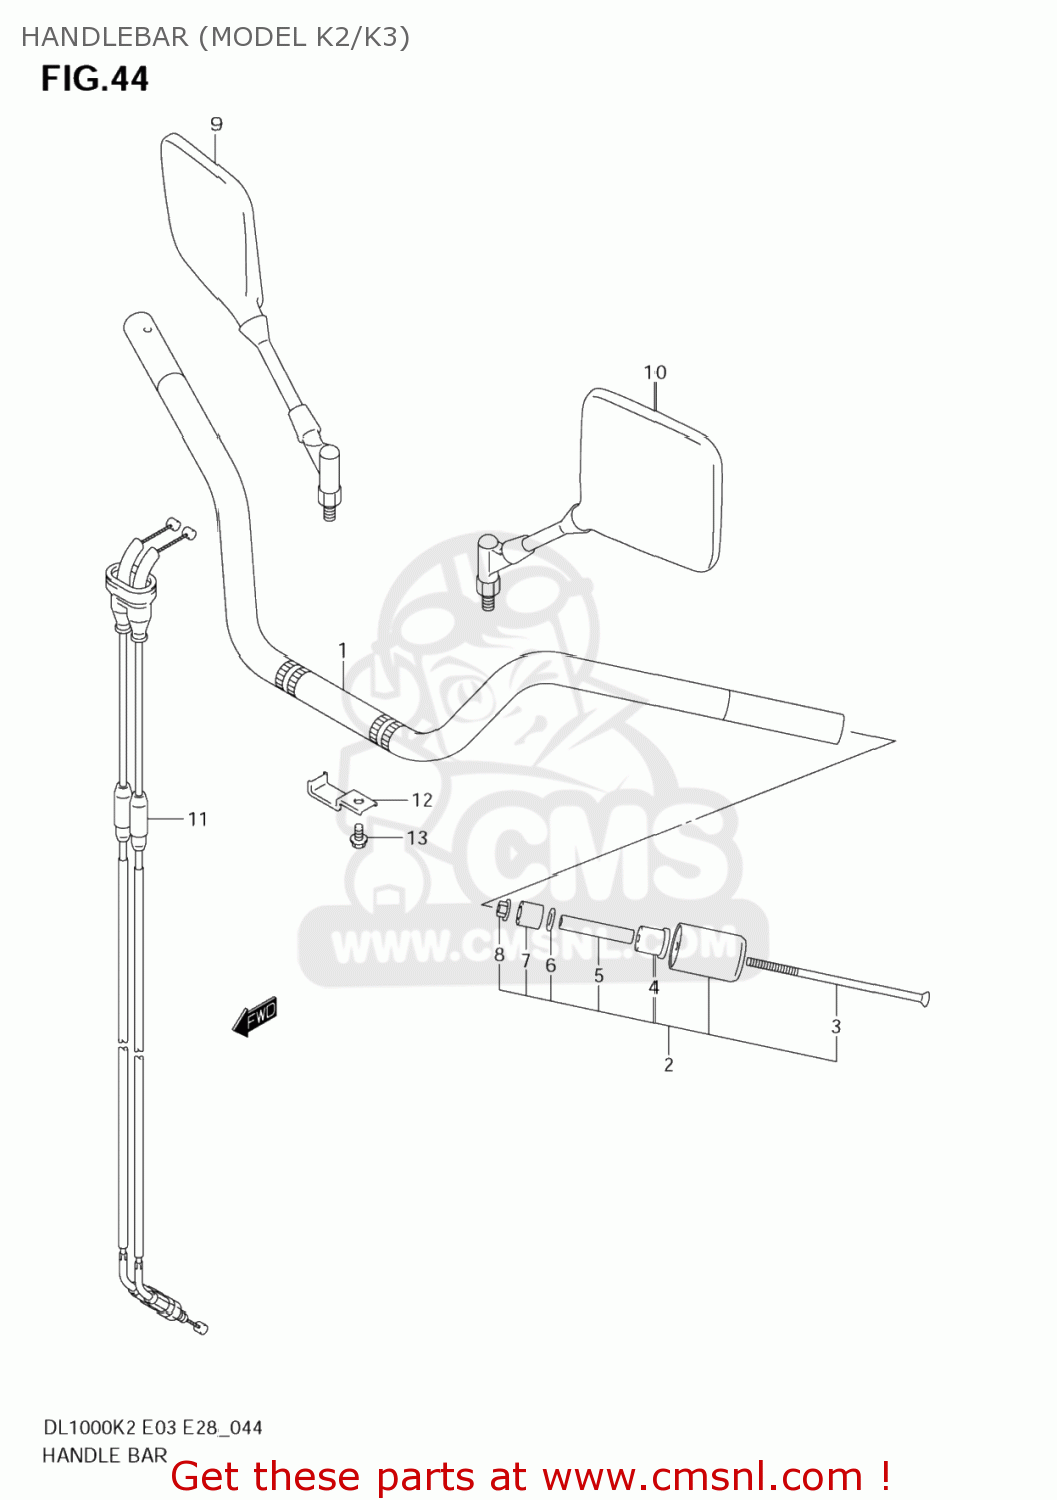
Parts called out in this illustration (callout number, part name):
1	HANDLEBAR
2	BALANCER SET,HANDLEBAR
3	SCREW(6X125)
4	EXPANDER
5	SPACER,EXPANDER
6	WASHER(6.5X16X1.6)
7	EXPANDER,HANDLE BALANCER
8	NUT
9	MIRROR ASSY,RE
10	MIRROR ASSY,RE
11	CABLE ASSY,THR
12	GUIDE,THROTTLE CABLE
13	BOLT
